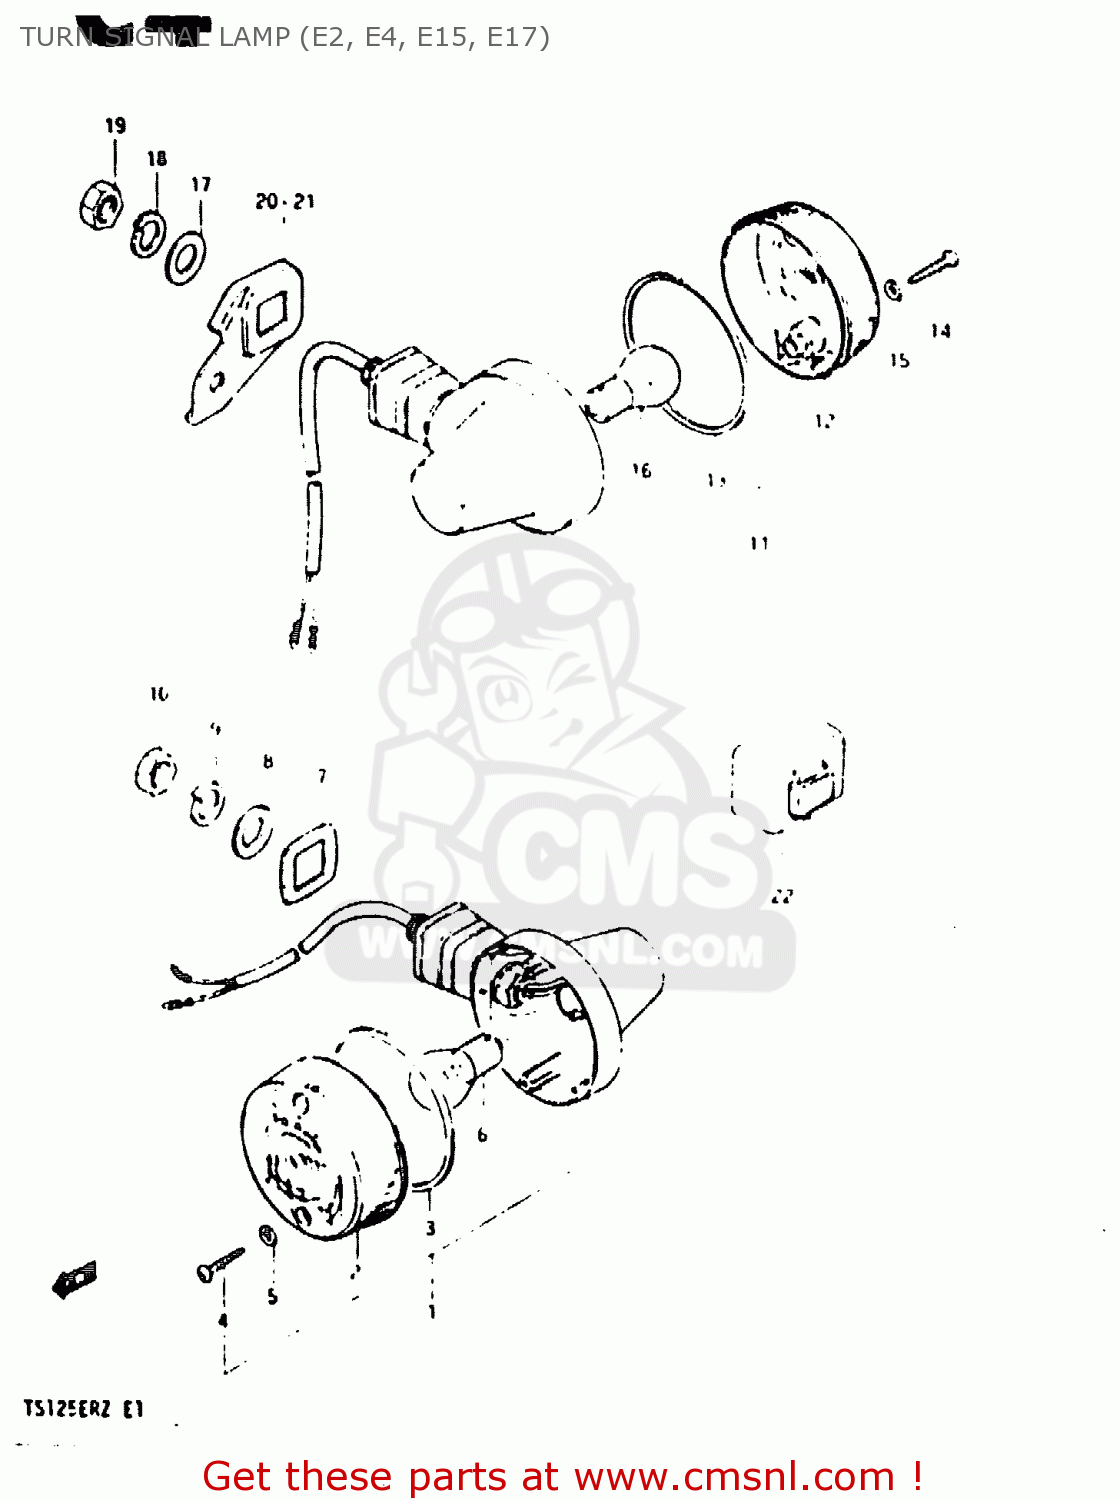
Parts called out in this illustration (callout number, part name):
1	LAMP ASSY, FRONT TURN SIGNAL
2	LENS
3	GASKET (NAS)
4	SCREW TAPP.
5	GASKET (NAS)
6	BULB 12V 21W
7	WASHER
8	WASHER
9	WASHER,LOCK 12
10	NUT
11	LAMP ASSY, REAR TURN SIGNAL
12	LENS
13	GASKET (NAS)
14	SCREW TAPP.
15	GASKET (NAS)
16	BULB 12V 21W
17	WASHER
18	WASHER,LOCK 12
19	NUT
20	BRACKET, REAR RH
21	BRACKET,RR TURNSIGNAL LAMP,L
22	RELAY,TURN SIGNAL
